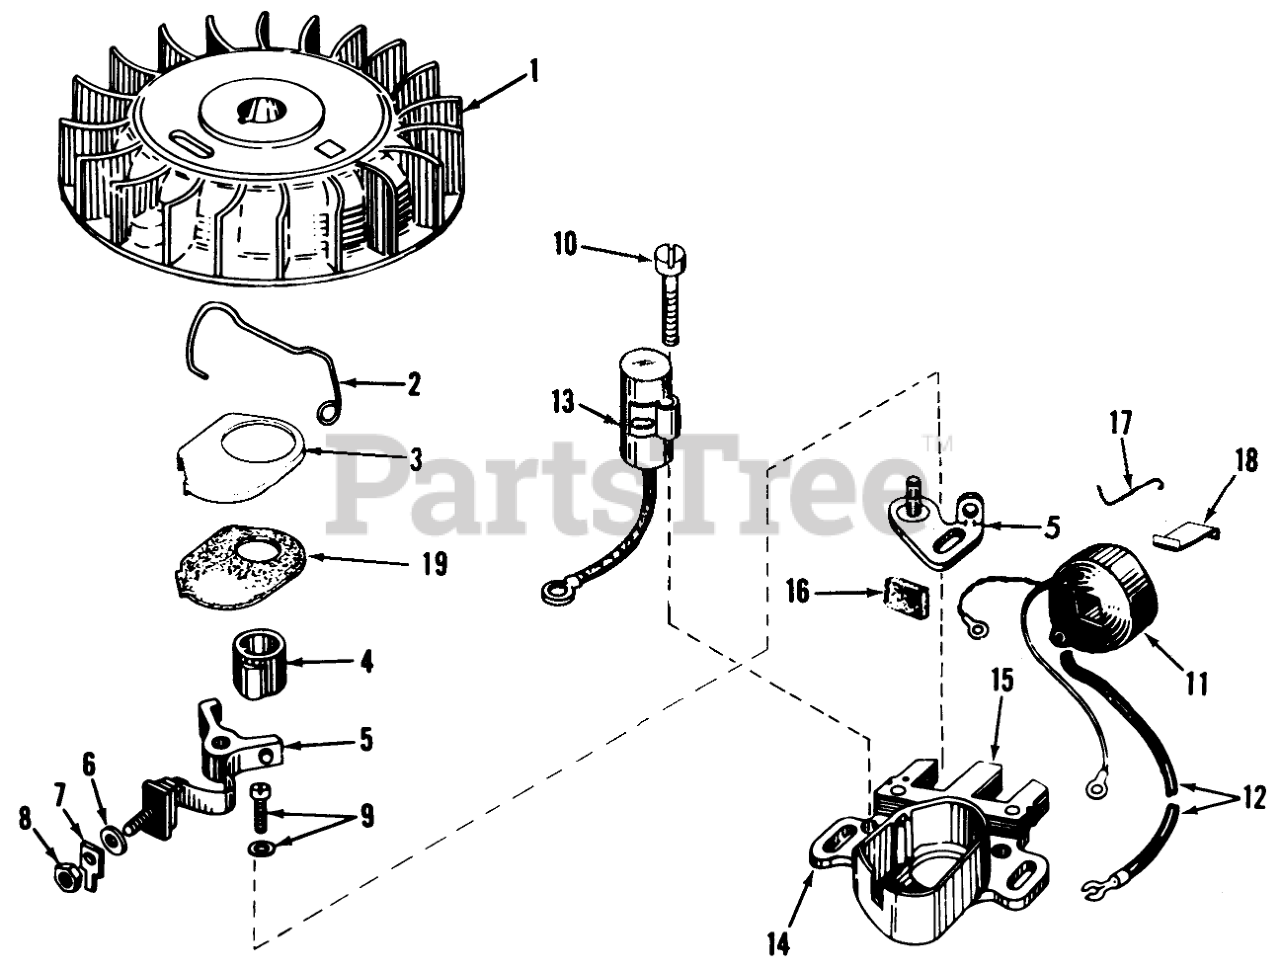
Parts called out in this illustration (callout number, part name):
1	Flywheel
2	Spring Breaker Box
3	Cover-Dust
4	Cam-Breaker
5	Breaker Assy.
6	Washer
7	Terminal, Ground
8	DECAL
9	Breaker Screw
10	Condenser Screw
11	Coil Assy. (Incl. #12)
12	Wire, Lead
13	Condenser
14	Core & Plate
15	Stator Assy. (Incl. #2, 3 5 thru 14 & 16 thru 19)
16	Felt,Cam Wiper
17	Clip, Coil
18	Spring Coil Wedge
19	Gasket-Dust Cover
19	Gasket, Dust Cover
